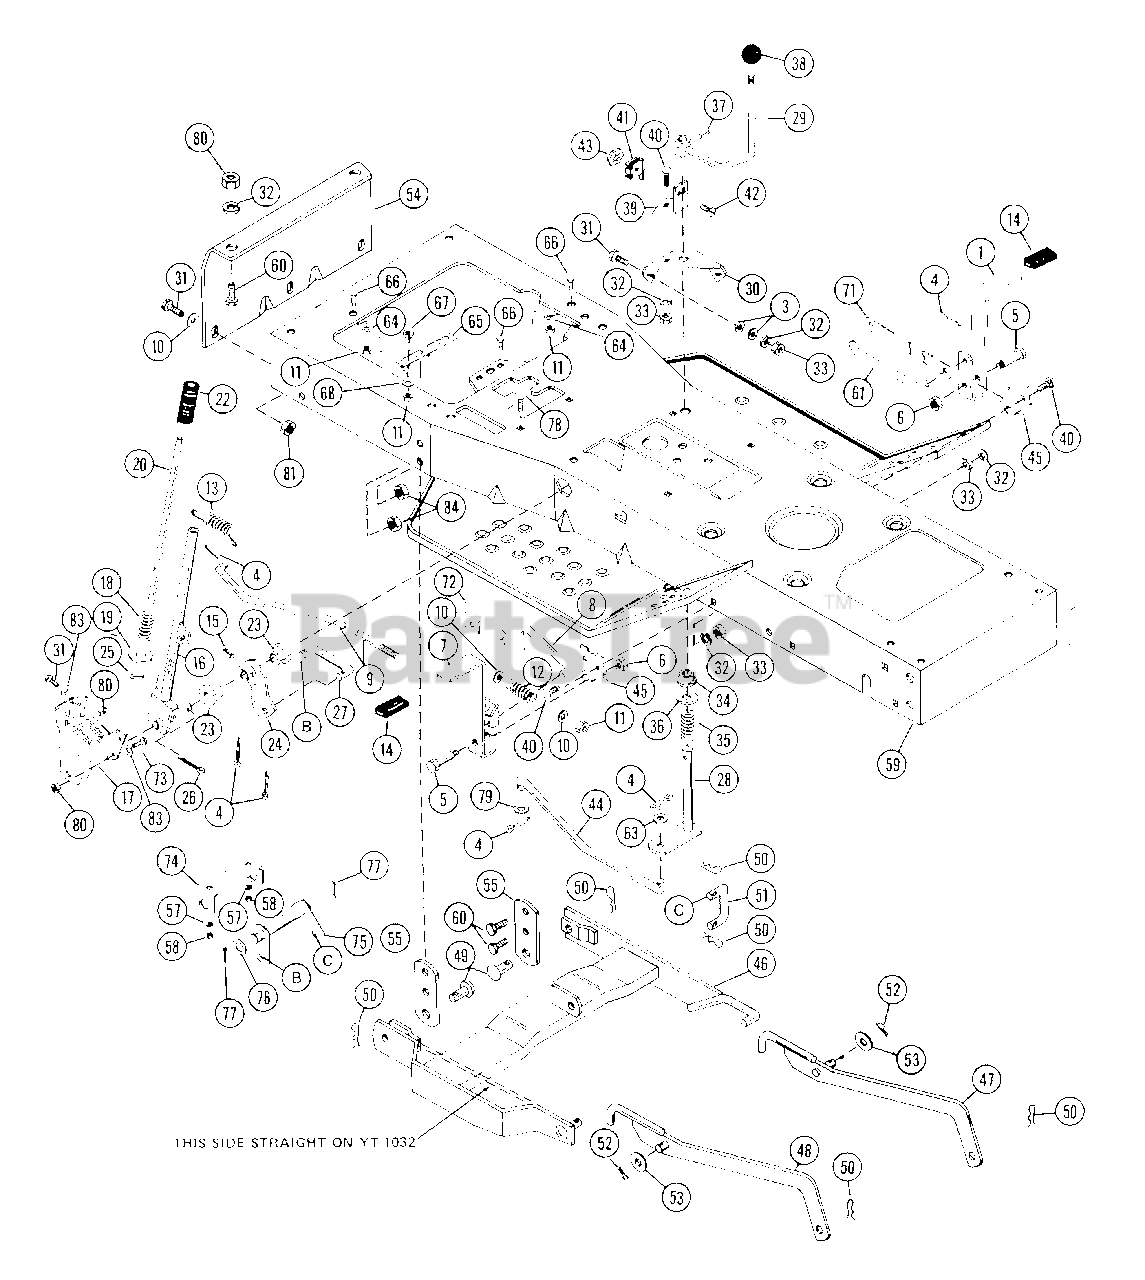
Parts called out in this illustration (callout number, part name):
1	CLUTCH PEDAL
2	NUT-LK-CTR .625-18 PL
3	WSHR-FL-STL.406X.812X.065PL
4	PIN-COTR .12X1.0 PL
5	SHOULDER BOLT .50 X 1.75
6	NUT-LK-JAM-CTR .375-16 PL
7	BRAKE PEDAL
8	PARKING BRAKE ROD
9	BRAKE ROD
10	WSHR-FL-STL .38X.875X.083 PL
11	NUT-LK .312-18 GR A PL
12	SG-COMP .102X.85X1.031
13	SG-TENS .072X.75X2.81 WLD ??
14	PEDAL COVER
15	PIN-GRV .250X1.25 TP E
16	LIFT HANDLE
17	LIFT QUADRANT
18	SG-COMP .048X.59X2.06 WLD9
19	WSHR-FL-STL .458X.750X.06 PL
20	PLUNGER ROD
21	PIN-ROLL .250X1.75
23	FLANGE BUSHING
24	LIFT ARM
25	PIN-ROLL .250X1.25
26	PIN-COTR .12X1.50 PL
27	LIFT LINK
28	PTO LEVER
29	P T O HANDLE
30	BRACKET
31	BLT-HEX .31-18X.75 PL GR5
32	WSHR-LK .312X.097 PL HVY
33	NUT-HEX .312-18
34	BSHG-FLG.500X.625X.312X.750NY
35	SG-COMP .080X.85X1.44
36	WSHR-FL-STL .531X1.062X.095 PL
37	PIN-ROLL .188X1.25
38	SHIFT BALL
39	SWITCH BRACKET
40	BLT-RDHDSQNK .31-18X.75 GR5 PL
41	SWITCH INTERLOCK
42	SCR-MCH 10-24X1.00 SLRH PL
43	NUT- .562-18
45	PEDAL PIVOT
46	REAR HANGER
47	RIGHT HANGER
48	LEFT HANGER
49	PIN-CLEV .494X1.25 YWZC
50	PIN-HAIR INT .09X.188 PL
51	LIFT LINK
52	PIN-HAIR INT .08X.38X1.42 YWZC
53	WSHR-FL-STL .531X1.062X.095 PL
54	DRAW BAR
55	HANGER BRACKET
57	WSHR-LK .375X.115 HVY PL
58	NUT-HEX .375-16
59	FRAME W/DECALS
60	BLT-HEX .38-16X.75 PL GR5
61	CLUTCH ROD
63	WSHR-FL-STL .438X1.0X.083 PL
64	BELT FINGER
65	CAM ACTUATOR
66	BLT-HEX .31-18X.88 PL GR2
67	SPACER -FLANGED .325X.498X.318
68	WSHR-FL-STL.312X.734X.065PL
73	BLT-HEX .31-18X1.75 GR5
74	CENTER LIFT BRACKET
75	CENTER LIFT LEVER
76	WSHR-FL-STL .754X1.125X.062 PL
77	PIN-COTR .12X1.50 PL
78	BLT-RDHDSQNK .38-16X.75 SHT PL
79	WSHR-FL-STL .438X1.0X.083 PL
80	NUT-LK-TOP .312-18 GR C PL
81	NUT-JAM .50-13 PL
82	ADJUSTOR ROD
83	WSHR-FL-STL.312X.734X.065PL
84	NUT-LK TOP .375-16 GR C YWZC
